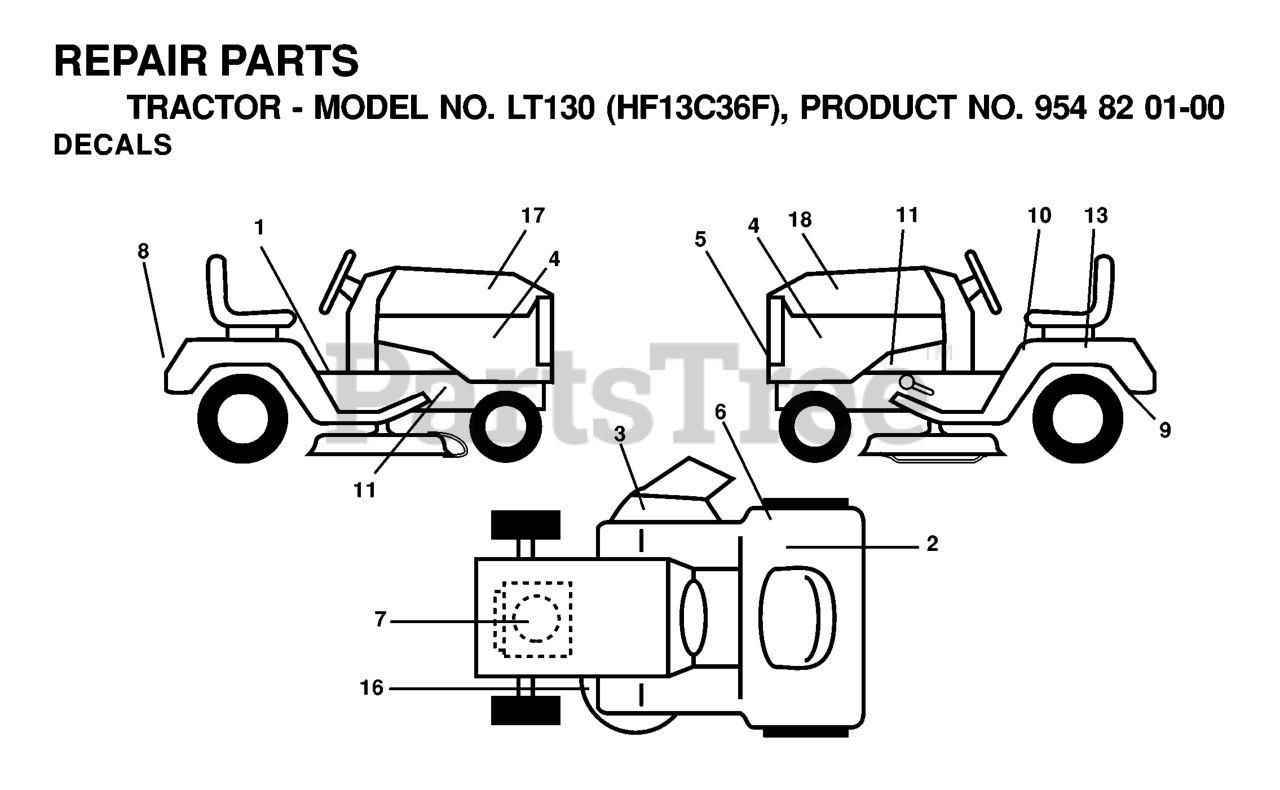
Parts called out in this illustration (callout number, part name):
1	Decal, Brake/Clutch Symbols
2	DECAL CERTIFICATION
3	DECAL MOWER CUT/FINGER
4	DECAL PNL SIDE
5	DECAL.GRILLE.HUSQ
6	DECAL EUROPE STANDARD CE
7	DECAL HP ENGINE
8	DECAL FENDER HUSQ
9	DECAL
10	DECAL READ OWNER'S MAN SYMS
13	DECAL BTRY SYMBOLS
